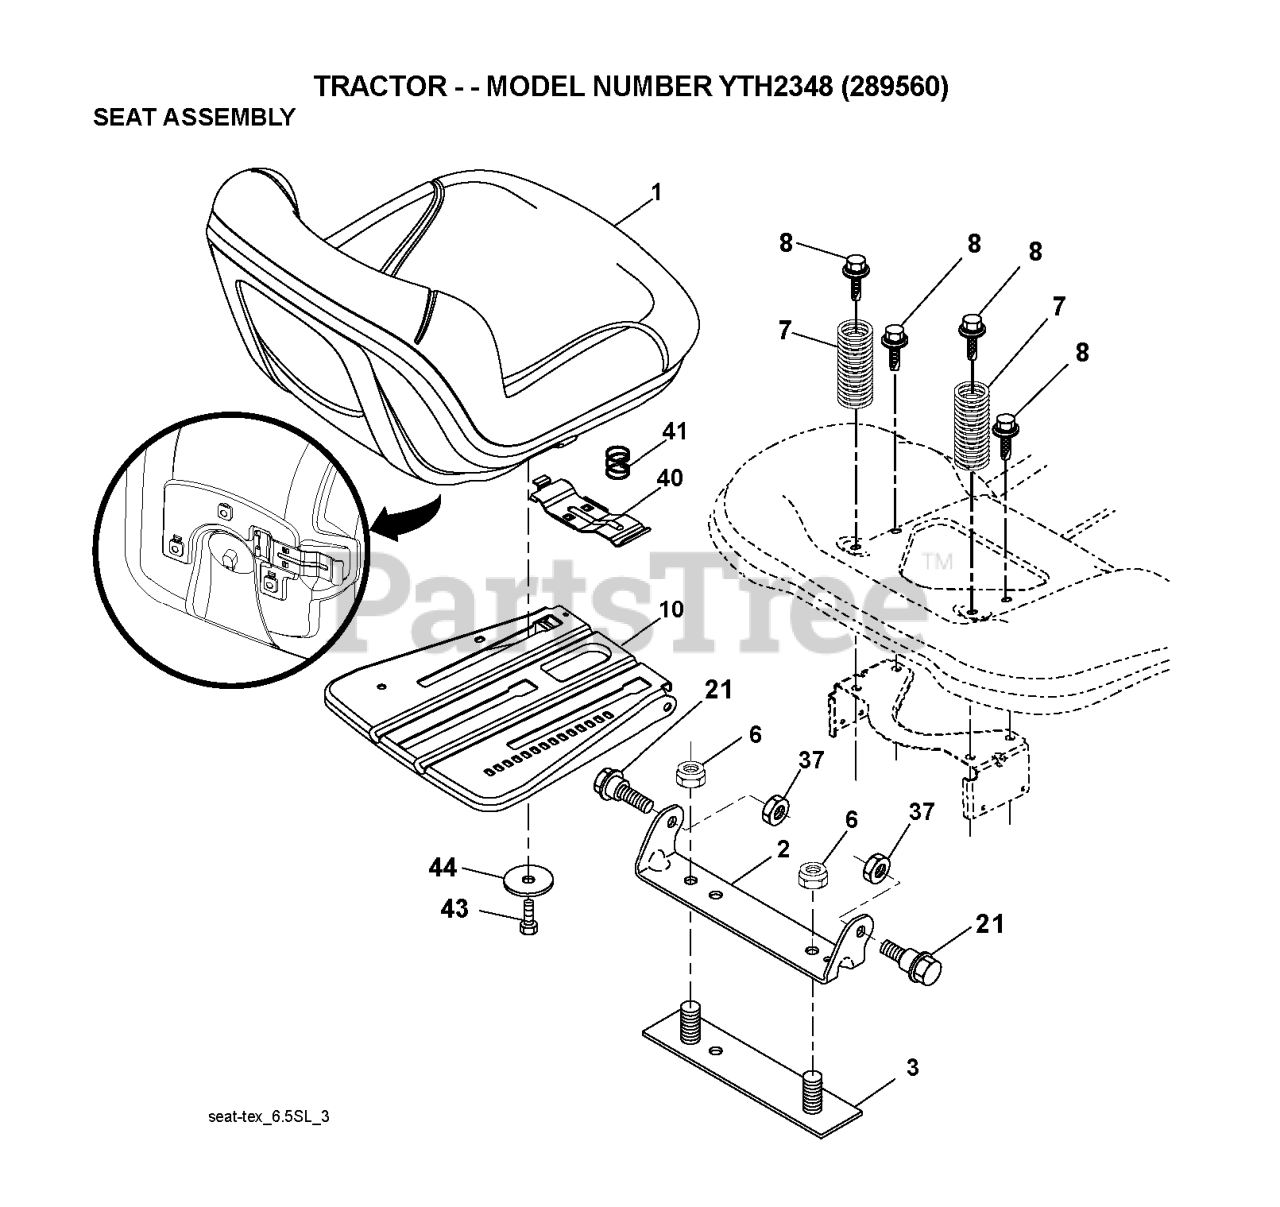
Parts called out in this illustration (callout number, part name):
1	RP SEAT, TH150, GREY, MILSCO
2	BRKT.PIVOT.FENDER
3	STRAP
6	NUT
7	SPRING COMPRESSION
8	BOLT.5/16-18UNCX3/4 W/SEMS.BLK
10	PAN.ASM.SEAT.3PT
21	BOLT.SHOULDER.5/16-18
37	NUT.71038.31-18.HEX.NYLOCK
40	HANDLE.SLIDE.SEAT.TEX.BLACK
41	SPRING.LATCH.SEAT.TEX
44	WASHER 13/32 X 2-3/8 X 12GA
